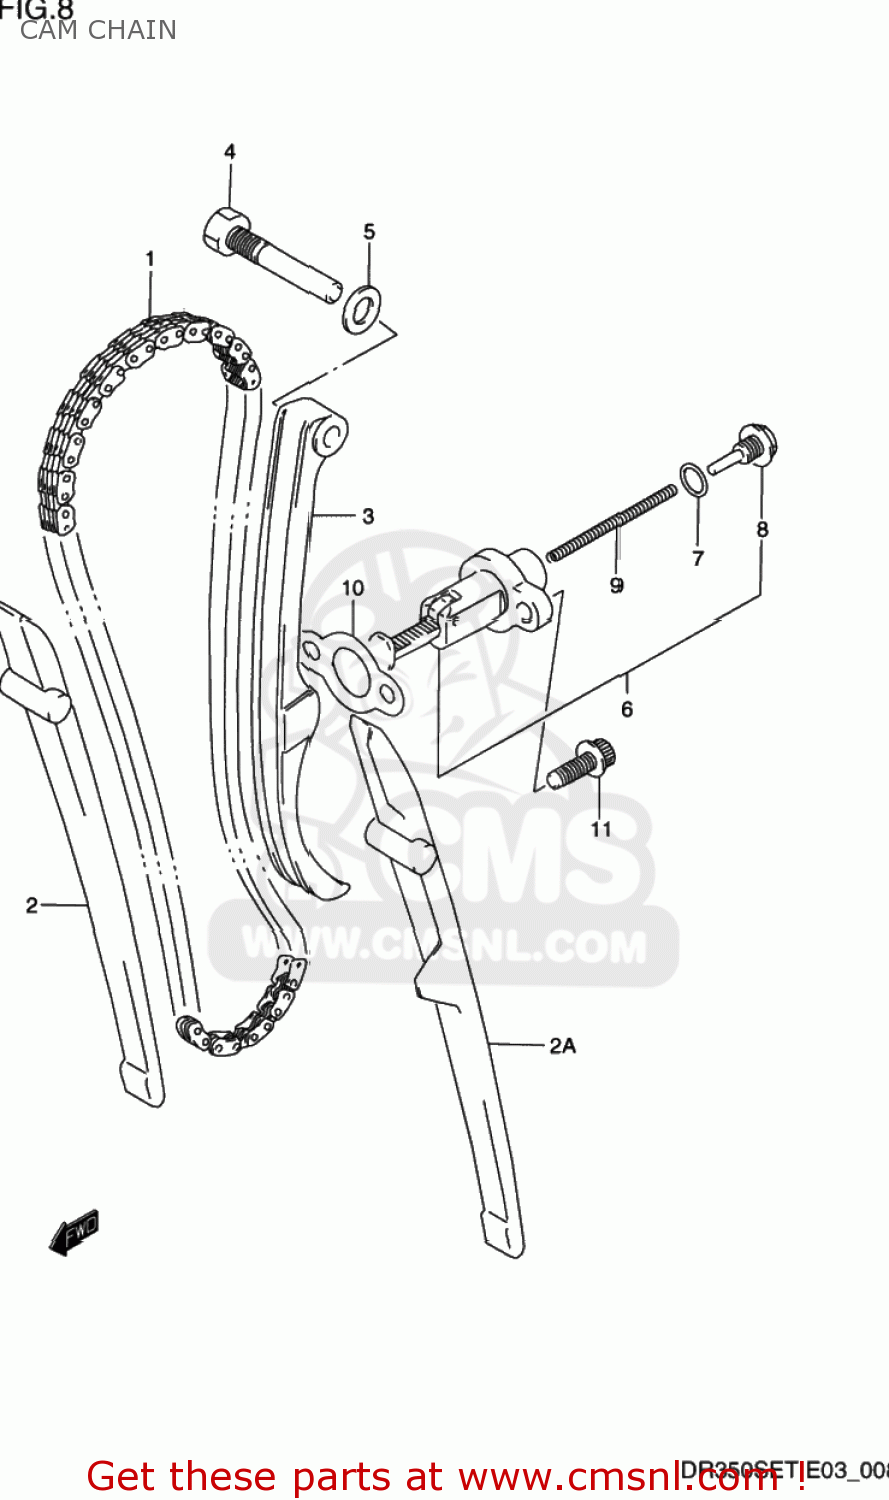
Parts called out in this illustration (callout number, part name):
1	CHAIN,CAMSHAFT DRIVE
2	GUIDE,CAM CHAIN
2A	GUIDE,CAM CHAIN
3	TENSIONER,CAM CHAIN
4	BOLT,CAM CHAIN TENSIONER
5	GASKET 8.2X14X1 (NAS)
6	ADJUSTER ASSY,TENSIONER
7	O RING
8	PLUG,ADJUSTER
9	SPRING
10	GASKET,TENSIONER ADJUSTER (NAS)
11	BOLT
